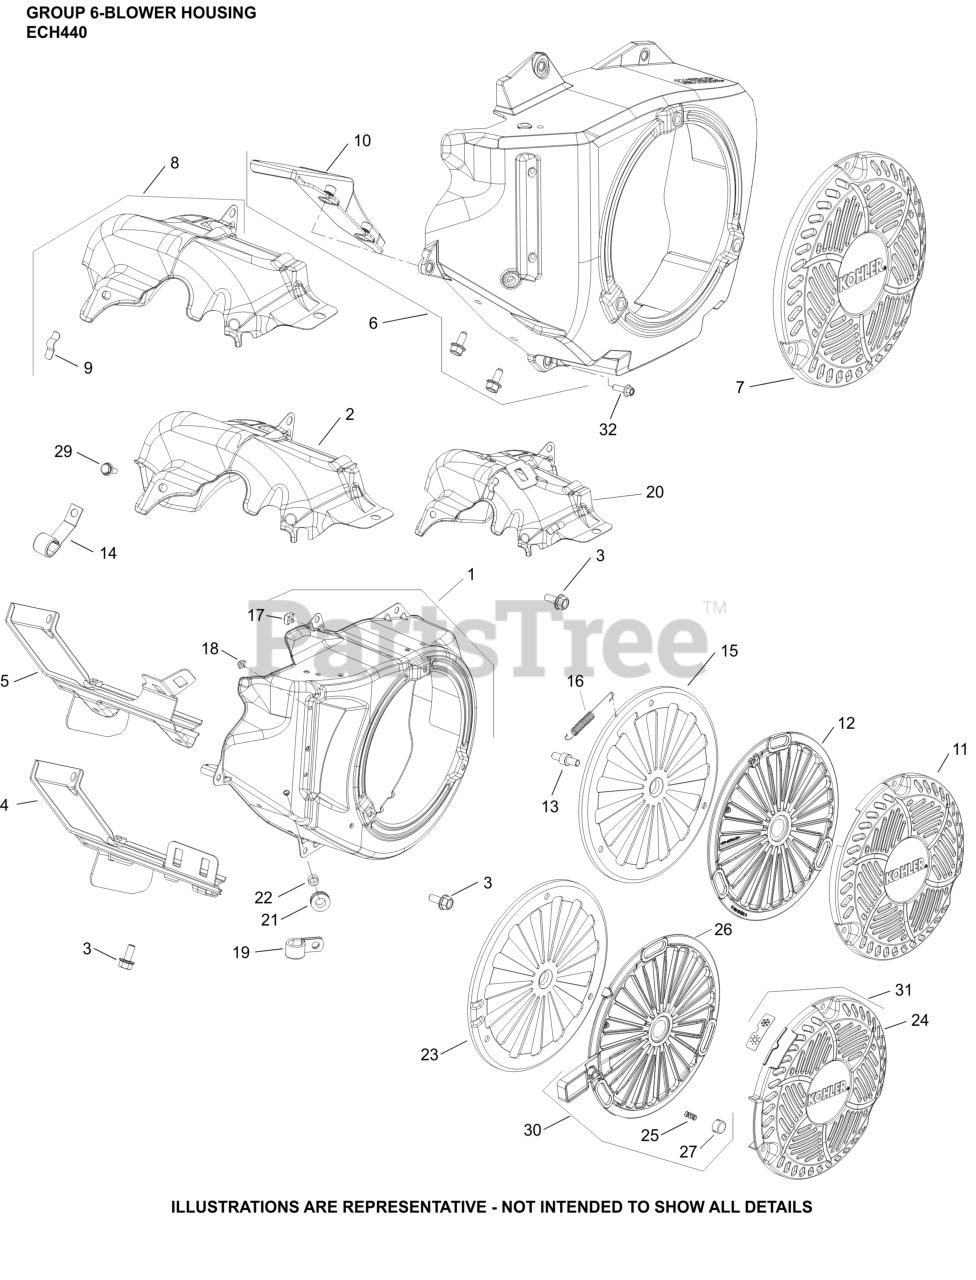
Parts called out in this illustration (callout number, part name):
1	KIT, BLOWER HOUSING
2	SHIELD, UPPER HEAT
4	SHIELD ASSEMBLY, CYLINDER
8	HEAT SHIELD ASSEMBLY
14	CLIP, CABLE
